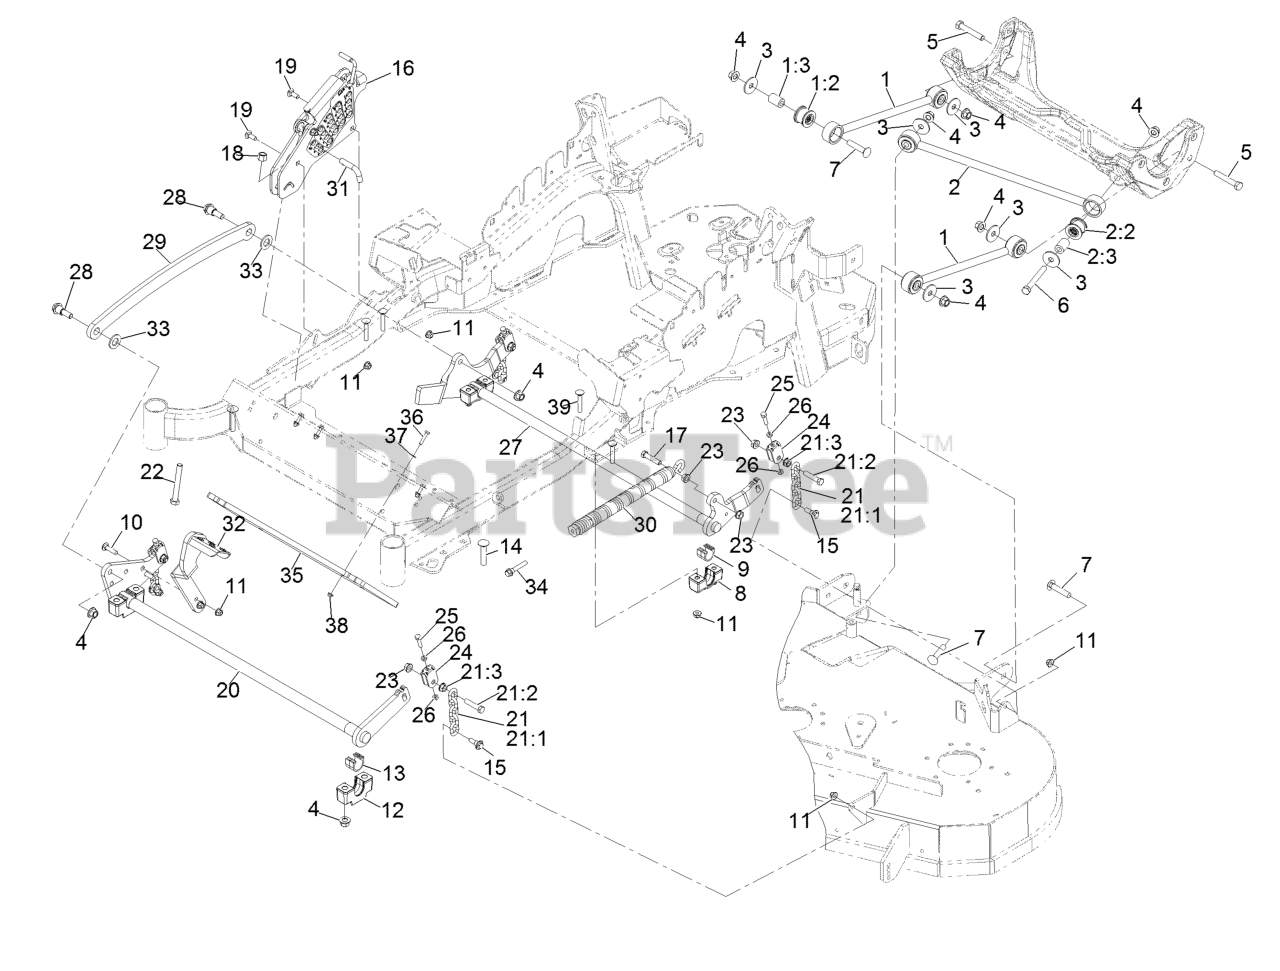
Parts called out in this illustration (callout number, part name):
1	DECK STRUT ASM
1:2	BUSHING-SUSPENSION, RUBBER
2	PANHARD ROD ASM
2:2	BUSHING-SUSPENSION, RUBBER
3	WASHER-THRUST
4	Nut-Lock 1/2-13
5	SCREW-HH
6	SCREW-HH
7	SCREW-CARR
8	SUPPORT-CROSS SHAFT, BEARING REAR
9	BEARING-CROSS SHAFT, REAR
10	SCREW-CARR
11	NUT-HF, NI
12	SUPPORT-CROSS SHAFT, BEARING
13	BEARING-CROSS SHAFT, FRON
14	Bolt-Carriage 1/2-13 X 2 1/2 Spl Neck
15	SCREW-SHOULDER, HHF
16	HOC ASM
17	SCREW-HH
18	NUT-LOCK, NI
19	BOLT-CARR
20	DECKLIFT-FRONT
21	DECK LIFT CHAIN ASM
21:1	CHAIN-LIFT, DECK
21:2	SCREW-HH
22	BOLT-TAP
24	YOKE-ADJUST, DECK
25	SCREW-HH
26	NUT-JAM
27	LIFT-DECK, REAR
28	SCREW-SHOULDER, HHF 1/2-13 X 1.12
29	LINK-LIFT, DECK
30	SPRING-EXTENSION
31	PIN-HOC
32	LEVER-FOOT
33	WASHER-FLAT
34	BOLT-SHOULDER
35	WEIGHT-TOE BOARD
36	SCREW-HH
37	WASHER-FLAT
39	Bolt-Carriage 3/8-16 X 2 1/4
